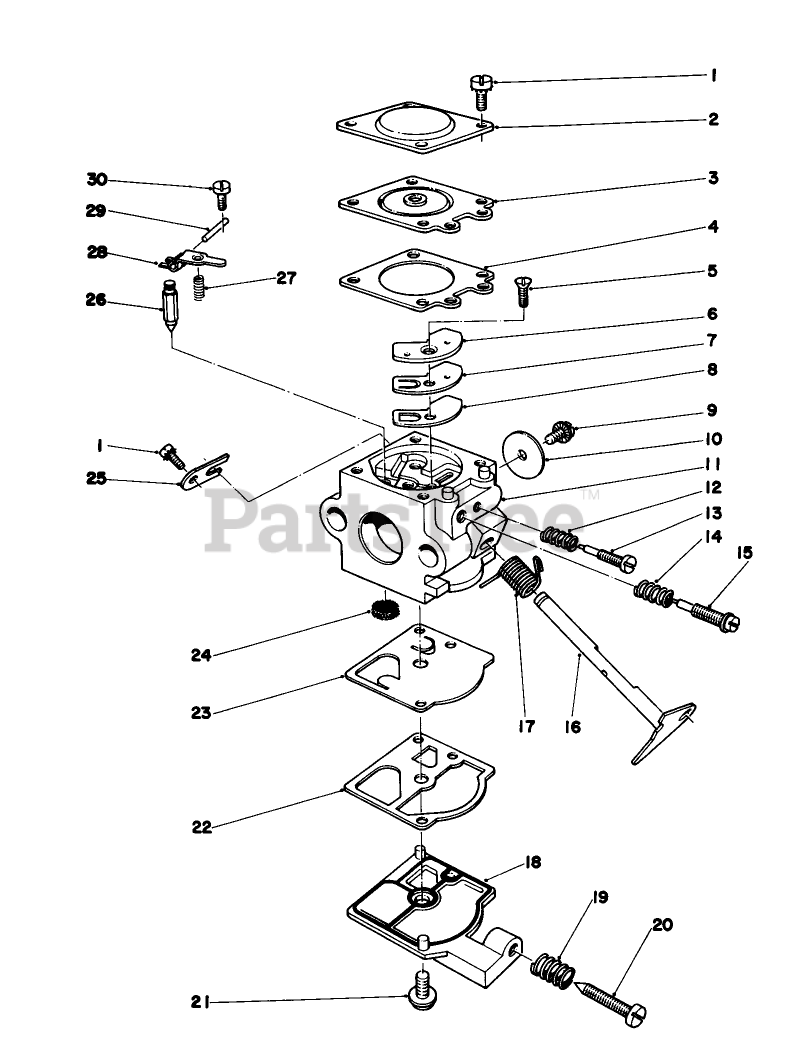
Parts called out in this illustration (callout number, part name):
1	Screw
2	Cover, Diaphragm
3	METERING DIAPHRAGM
4	Gasket, Diaphragm
5	Screw-Circuit Plate
6	Plate, Circuit
7	Diaphragm Circuit Plate
8	Gasket-Circuit Plate
9	Screw
10	Valve, Throttle
11	Carburetor Assembly
12	Spring, Needle
13	Needle-Idle
14	Spring, HS Needle
15	Needle, HS
16	THROTTLE SHAFT ASM
17	Spring-Throttle Lever
18	Cover, Fuel Pump
19	Spring, Idle Screw
20	IDLE ADJUST SCREW
21	Screw
22	PUMP GASKET
23	Diaphragm Fuel Pump
24	Screen Inlet
25	Clip Throttle Shaft
26	INLET NEEDLE VALVE
27	Spring, Lever
28	Lever Metering
29	Metering Lever Pin
30	Screw-Metering Pin
